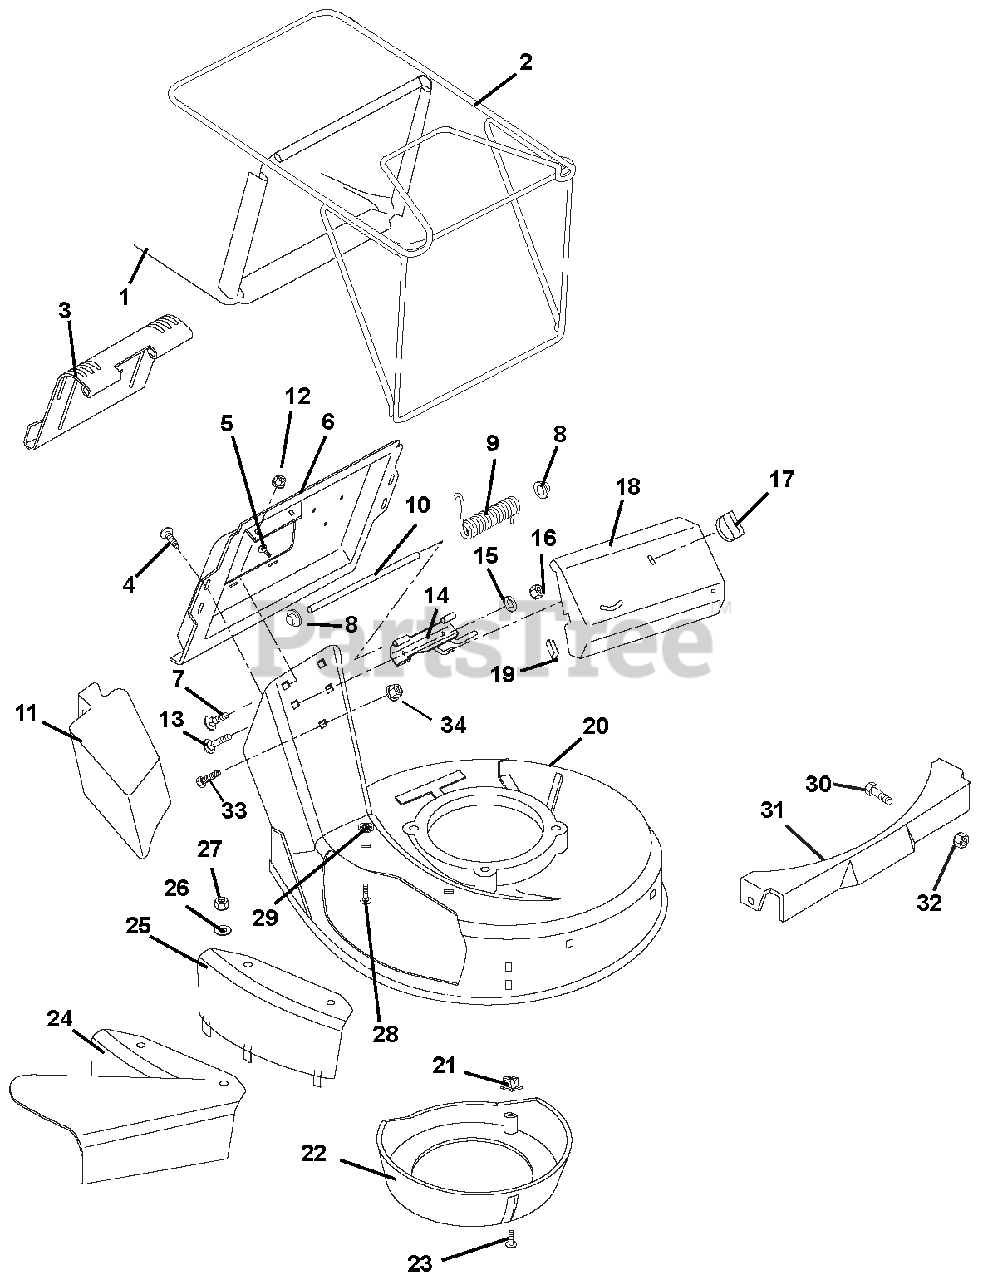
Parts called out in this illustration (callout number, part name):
1	BAG, CONSUMER BLACK 15 OZ/YD2
2	FRAME, WBLM BAGGER
3	CATCHER PLATE DOOR
4	@SCR-TAP 12-24X.50 HWH TR YWZC
5	SCR-TAP 10-24X.375 TORX PHD YZ
6	CATCHER PLATE
7	@BLT-RDHDSQNK .25-20X.50 G5YZ
8	PUSH NUT, .25
9	SG-TORS .120X.68X3.09
10	DOOR PIN
11	MULCH MASTER PLUG
12	@NUT-SPNLK-FLG .25-20 YWZC
13	@BLT-RDHDSQNK .25-20X.75 G5YZ
14	HINGE BASE WELDMENT
14	HINGE BASE
15	WSHR-LK .250X.077 HVY YWZC
16	@NUT-HEX .25-20 YWZC
17	WING - NUT
18	COVER, LM DRIVE
19	TRIM BUMPER
20	MOWER PAN HEAD W/SFTYDECALS SP
20	MOWER PAN W/SAFETY DECALS PUSH
21	PLASTIC GROMMET
22	CENTER BAFFLE
23	SCR-TAP 10-16X.62 SLPH AB YWZC
24	SIDE DISCHARGE ASSEMBLY
25	COVER, SIDE DISCHARGE
26	@WSHR-FL-STL.406X.812X.065 YWZ
27	@NUT-LK-NYL .312-18 YWZC
28	BLT-RDHDSQSHK.31-18X.75 GR2 YW
29	NUT-PUSH .312
30	@BLT-RDHDSQNK .31-18X.50 G5YZ
31	PANEL-FRONT
32	@NUT-LK-TOP-FLG .31-18 YWZC
33	@BLT-HEX .38-16X.50 GR5 YWZC
34	@NUT-SPNLK-FLG .375-16 YWZC
